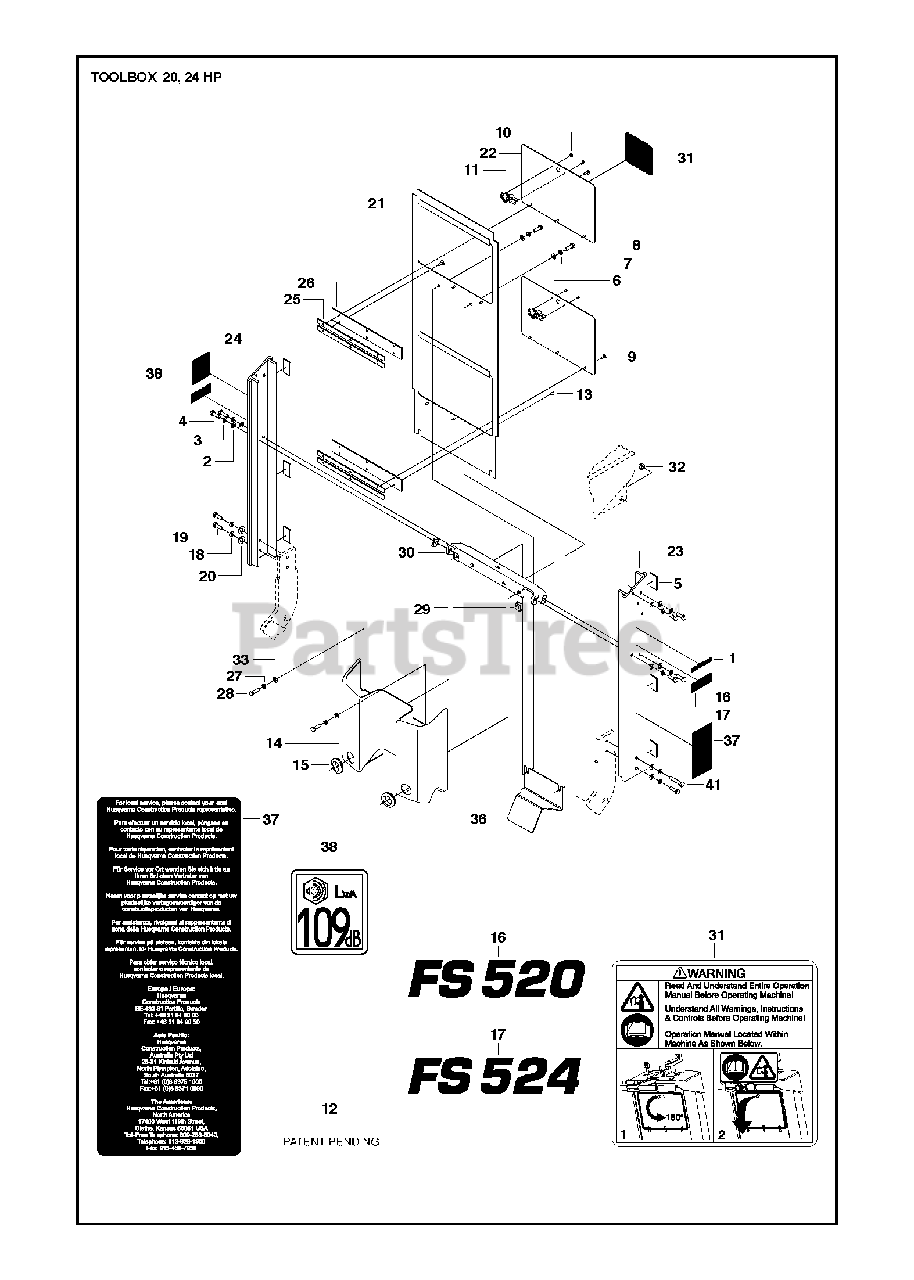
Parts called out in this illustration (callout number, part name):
2	WASHER
3	SPRING WASHER
6	WASHER
7	SPRING WASHER
18	SPRING WASHER
20	WASHER
27	SPRING WASHER
32	HEXAGON LOCKING NUT
33	WASHER
41	SCREW EHHM
